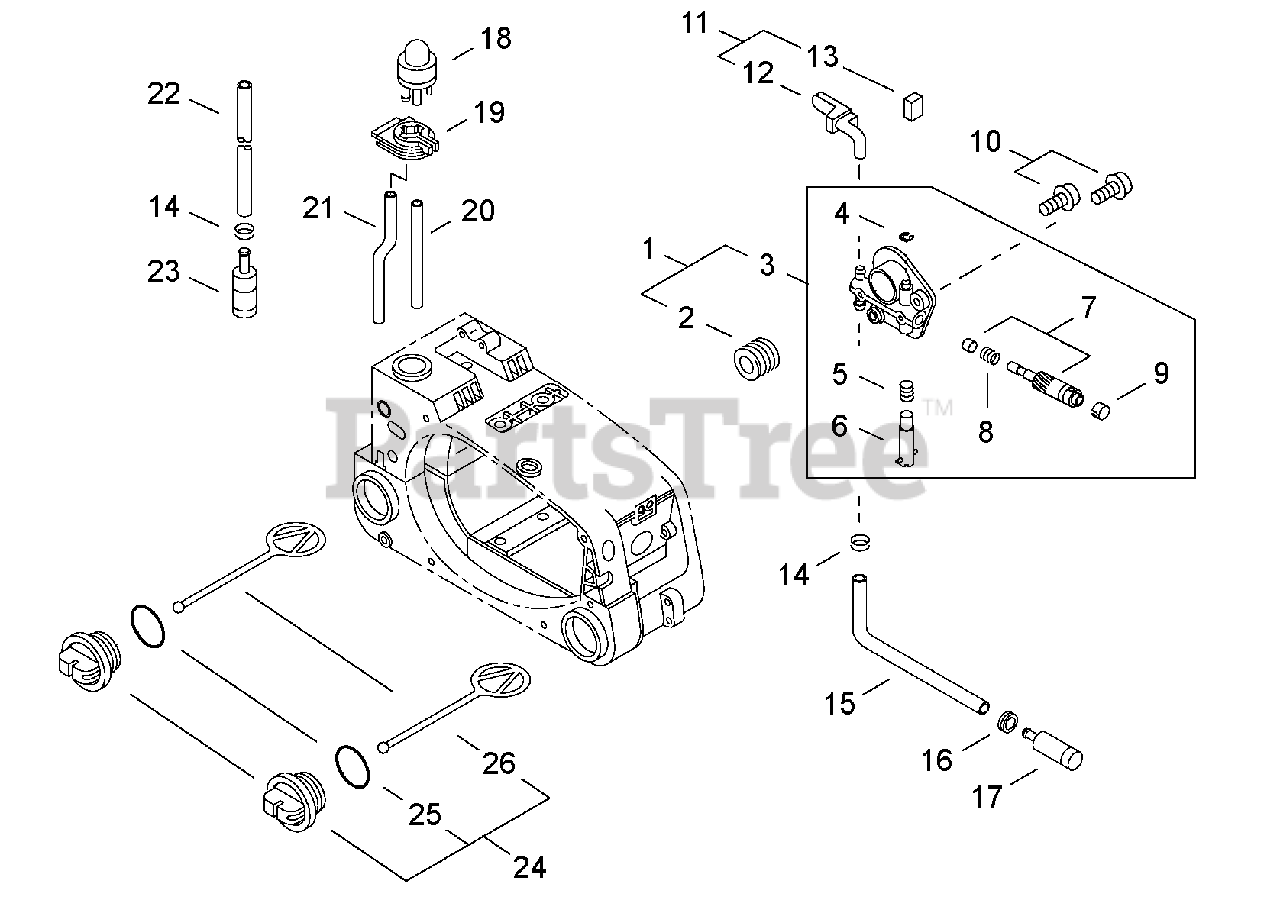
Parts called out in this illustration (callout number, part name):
1	AUTO-OILER ASSY
2	GEAR - WORM
3	AUTO-OILER ASSY
4	RING, RETAINING
6	NEEDLE, ADJUST
7	PLUNGER
9	CAP, OIL PUMP
10	SCREW - 5X12
11	OIL TUBE KIT
12	PIPE - OIL
13	PAD, FOAM
14	CLIP - 6.5
15	PIPE - 3X6X115 -- BLACK
16	GROMMET
17	FILTER, OIL
18	PUMP, PURGE
20	PIPE - 3X5X70 -- BLACK
21	PIPE - 2X4X42 -- CLEAR
22	PIPE, FUEL - SPIRAL
23	FILTER, FUEL
24	CAP ASSY - BLACK
25	O-RING - 25
26	CONNECTOR, CAP
